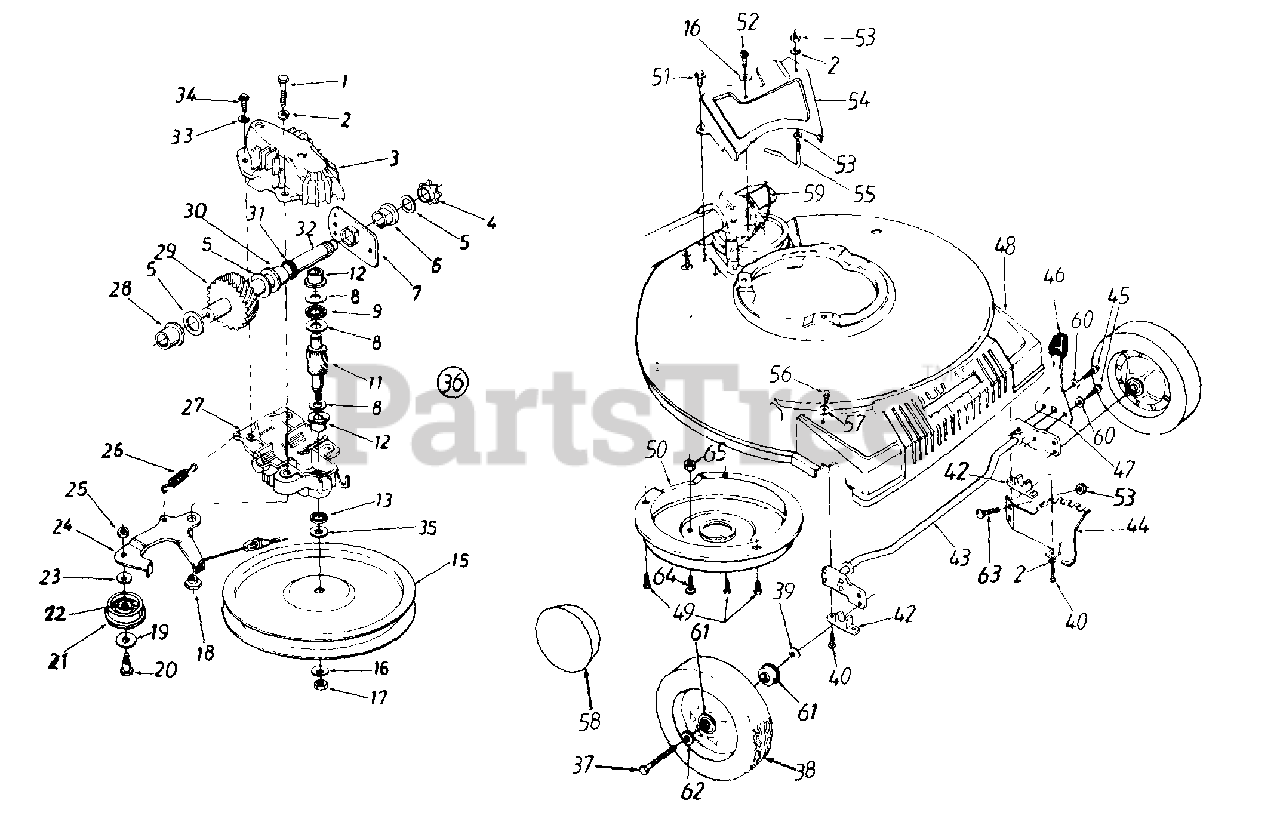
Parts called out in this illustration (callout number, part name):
1	Hex Patch Bolt 1/4-20 x 1.25"
2	L-Wash. 1/4" I.D.
3	Upper Hsg. Half
4	#48 Sprocket 7T x 1/2 Pitch
5	Fl-Wash. 5/8" I.D. x .030
6	Hex Flange Brg..631" I.D.
8	Thrust Wash..382" I.D. x .70" O.D.
9	Thrust Bearing .375" I.D. x .812" O.D.
11	11 Tooth Pinion Shafts
12	Flange Bearing
13	Oil Seals
15	Fl-Pulley 5.06" O.D.
16	Bell-Wash..265" I.D. x .75"
17	Hex L-Nut 1/4-28 L.H. Thd.
18	Shld. Spacer .375" Dia. x .170
19	F1-Wash..390" I.D. x 1.0"
20	Shld. Bolt .375" Dia. x .40"
21	Fl-Idler Plastic 1.50" Dia.
22	Needle Brg..375" x .31
24	Idler Brk't. Ass'y.
25	Hex Patch L-Nut 1/4-28 Thd.
26	Extension Spring 1.12" Lg.
27	Lower Hsg. Half
28	Flange Bearing .566 Dia.
29	33 Tooth Helical Gear
30	Flange Bearing .629 Dia.
31	Oil Seal .625 Dia.
32	Gear Sprocket Shafts
33	L-Wash. #10 I.D.
34	Hex B-Tap Scr. #10 x .62"
35	Hex Washer .26" x .88"
36	Transmission Comp.
37	Front Axle Bolt
38	Wheel Ass'y. Comp.
39	Bell-Wash..380" I.0. x.88
40	Hex Wash. Hd. Tap Scr. 1/4-20 x 1" Lg.
42	Block Bushing
45	Hex TT-Tap Scr. 1/4-20 x .38"
46	Knob
47	Spring Lever
48	Plastic Front End
49	Hex B-Tap Scr. 1/4" x .38"
52	Hex Wash. Hd. B-Tap Scr. 1/4 x .62"
53	Hex Flange L-Nut 1/4-20 Thd.
56	Torx Scr. 5/16 x .75" Lg.
57	Bell-Wash..345" I.D. x.88"
58	Hub Cap
59	S.P. Cable 44" Lg.
60	External L-Wash. 1/4" I.D.
61	Ball Bearing 1/2" I.D.
62	Wave Wash..53" I.D. x .78"
63	Carriage Bolt .5" Lg.
64	Mach. Scr. 1/4-20 x 2" Lg.
65	Hex L-Nut 1/4-20 Thd.
